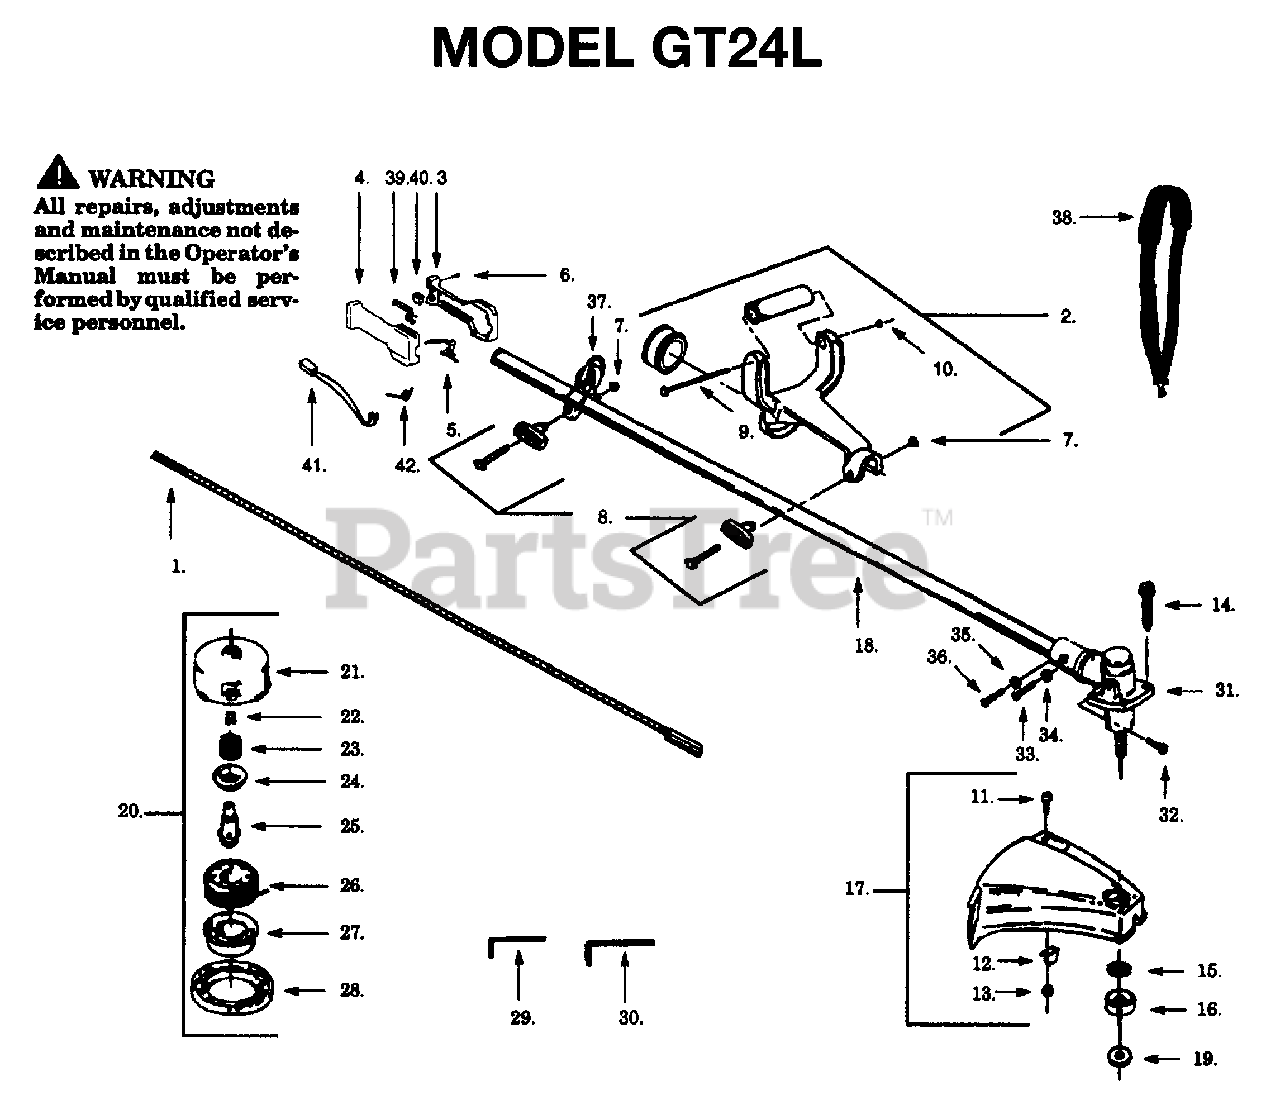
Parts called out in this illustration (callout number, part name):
1	SHAFT-FLEX (57").
2	ASS'Y-HANDLE ANTIVIB
5	THROTTLE TRIGGER
6	SCREW-10-14 X 13/16 (PL
8	KIT "T" HANDLE
9	SCREW-12-24 X 4-11/16 P
10	NUT-12-24 (HEX)
12	LIMITER-LINE
13	NUT 10-24 NYLOC HEX
14	SCREW - SHIELD
17	KIT-SHIELD
18	DRIVE SHAFT HOUSING
19	WASHER-GRASS
20	TAP-N-GO I CCW
21	ASSY-HUB W/LN SAVER
22	SAVER-LINE
24	ADAPTOR SPRING
25	GEAR-DRIVE
27	TAP BUTTON
29	HEX WRENCH 5/32
30	HEX KEY 3/16"
31	GEAR BOX ASSY/TYPE 1
32	SCREW-5/16-24X3/8 HEX S
33	SCREW-10-24 X 7/16 (HEX
34	LOCKWASHER-LOCATOR-TYPE 2
35	LOCKWASHER
36	SCREW-1/4-20X1 HEX SOC
37	ASSY-CLAMP HARNESS
38	STRAP SHOULDER
42	SPRING-LEVER RETURN
